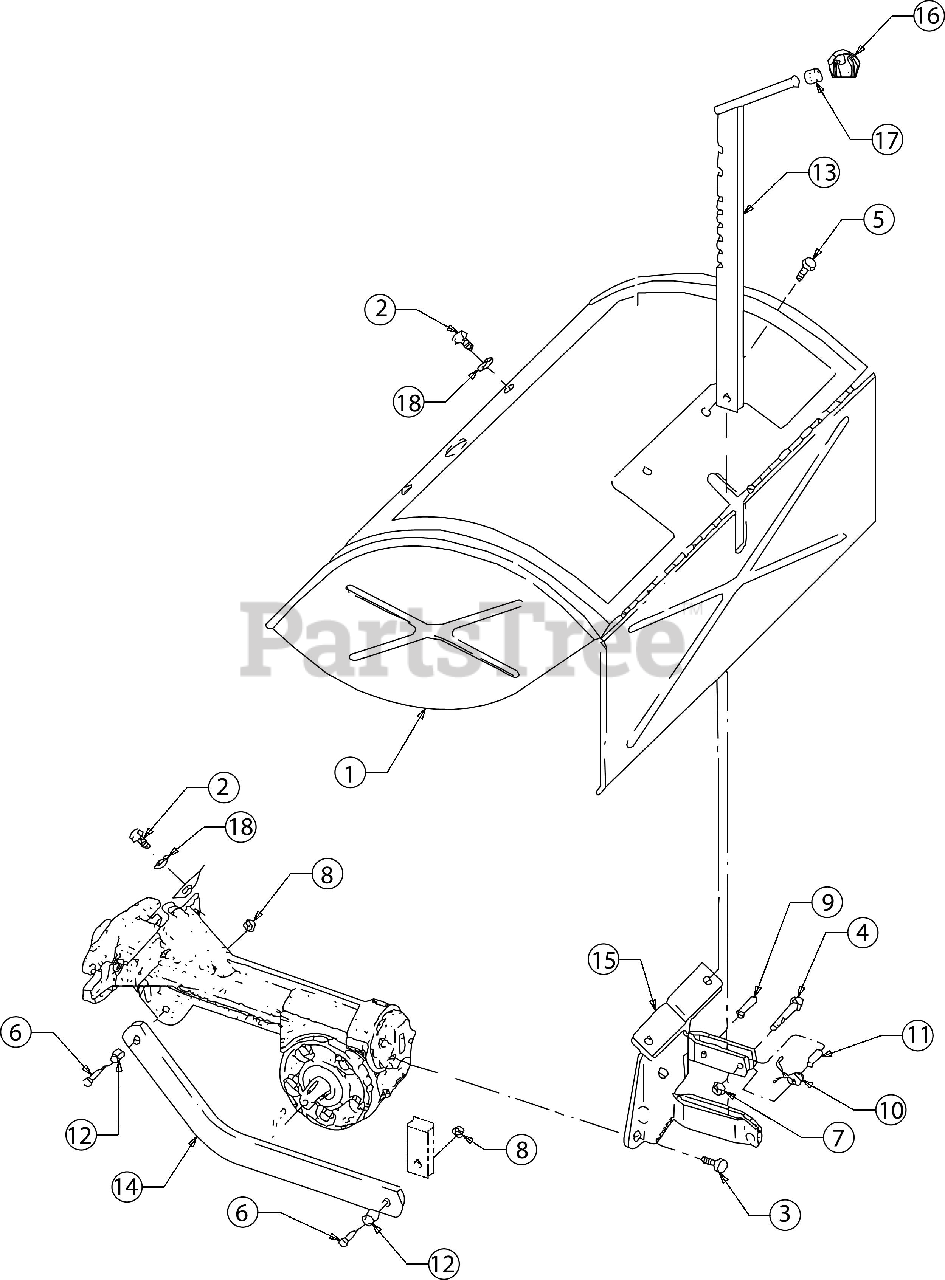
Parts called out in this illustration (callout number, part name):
1	TINE HOOD ASSEMBLY
2	SCREW 5/16-18
3	HEX SCREW 5/16-18 X .625 GR5
4	SCREW 1/4-20 X1.00 GR5
5	SCREW 1/4-20 X.500
6	SCREW 3/8-16 X 1.25 GR5
7	FLANGE LOCK NUT
10	TORSION SPRING
11	SPLIT SPACER
12	BUSHING .5 X
13	BAR DEPTH REGULATOR
14	DEPTH REGULATOR
15	BRACKET-HOOD
16	CONTROL KNOB
17	RING-TOLERANCE
18	WASHER-#1.125X.344
